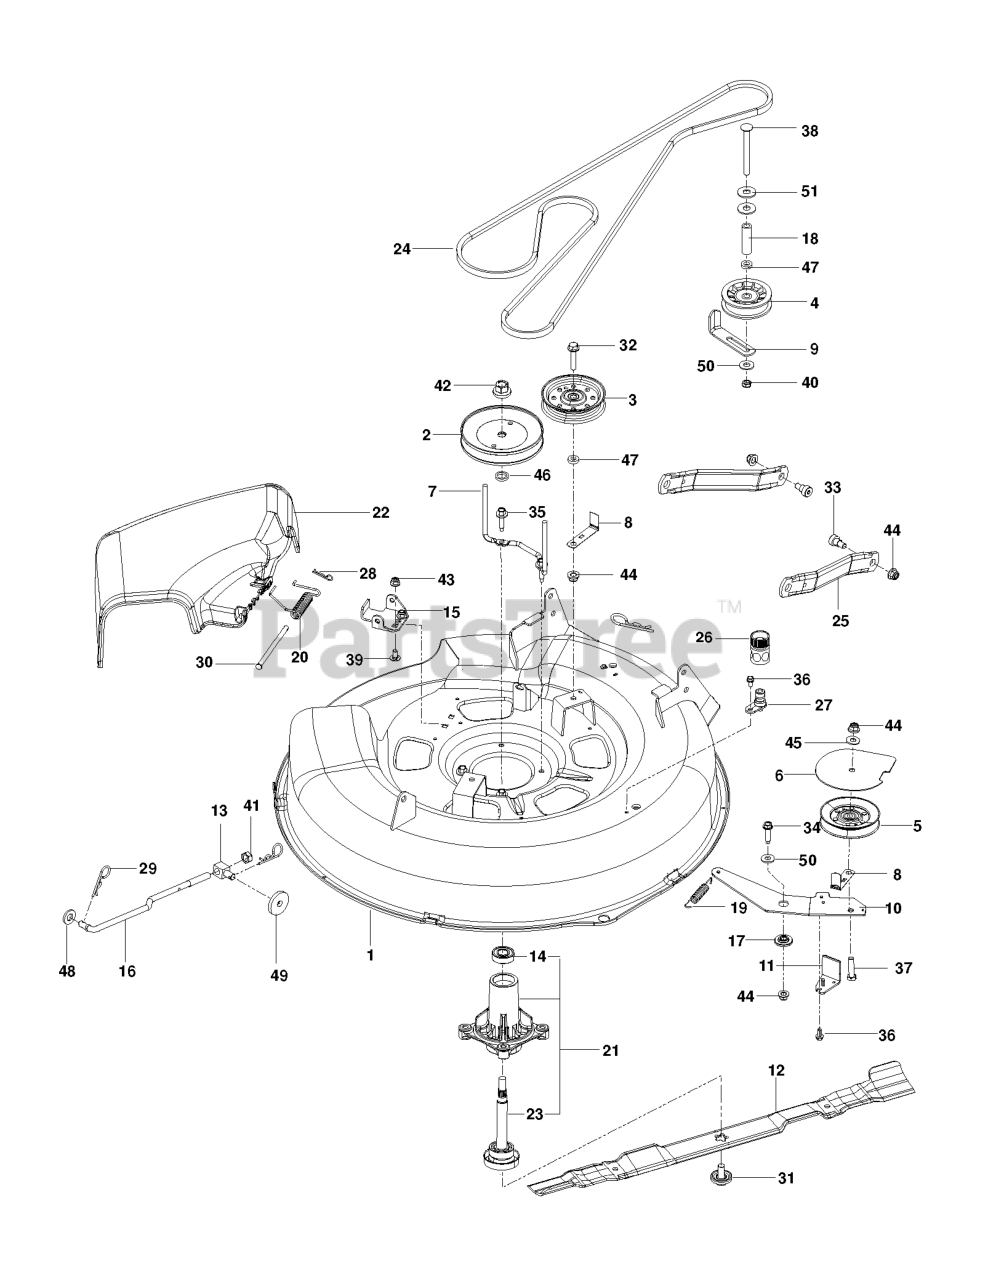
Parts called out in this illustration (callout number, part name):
1	DECK.SVC.W/DECALS.30".RZ.ORN
2	PULLEY MANDREL 5.0"
3	PULLEY.IDLER.FLAT.46.PR.DR.
4	PULLEY, IDLER RAKE & ZTR
5	PULLEY.IDLER.4.25
6	COVER, PULLEY, BLACK
7	BELT KEEPER.MANDREL.38"COATED
8	KEEPER.BELT.30"SRD
9	GUIDE, BELT
10	ARM.IDLER.30".RZ.X431
11	RP ARM.BRAKE.MOWER.38"LH.TEX
12	BLADE.MOWER.BAGGING.30"
13	SWIVEL.TRUNION.LINK.DECK.FRONT
15	BRKT.DEFLECTOR.38"2005+
16	LINK LIFT SUSP. FRONT MOWER
17	SPACER.RETAINER
18	SPACER .39 ID X 2.25
19	SPRING.BRAKE.RETURN.38"
20	TORSION SPRING
21	MANDREL.ASM.SUB-NON.GR
22	SHIELD.DEFLECT.MWR.30S.BLACK
23	SHAFT.ASM.MDRL.N/GREASE.38
24	BELT DECK 99.60 EFL
25	ARM.SUSPENSION.MOWER
26	COUPLING.QUICK CONNECT
27	PORT.WASHOUT
28	HAIRPIN #2
29	HAIRPIN #4
30	PIN-CLEVIS 5/16 DIA X 5.19 ZD
31	BOLT.WASHER.ASM.7/16-2
32	BLT 3/8-16X1-3/4 WHIZLK ZN SP
33	SB 3/8-16 X 3/8 SKT HD ZD
34	HHFS 3/8-16 X 1.50 GR5 ZD
35	WASHER HEAD SCREW
36	BOLT 1/4-20 X 1/2 HWST
37	HCS 3/8C X 2
38	RHSNB 3/8-16 X 4 GR5 ZD
39	CARRIAGE BOLT 5/16C X 5/8"
40	NUT 3/8-16 HEX JAM
41	NUT, 7/16-20 HEX NYLOC ZC
42	LOCKNUT - 9/16
43	5/16-18 NYLOC FLANGE NUT
44	NUT 3/8-16 HEX FLG NYLOC ZD
45	WASHER 3/8 SAE FLAT
46	WASHER-SPACER
47	WASHER 3/8 X 3/4 X .187 TK
48	WASHER 1/2" FLAT
49	SPINDLE WASHER
50	WASHER 3/8 FLAT
51	WASHER 7/16 FLAT ZD
